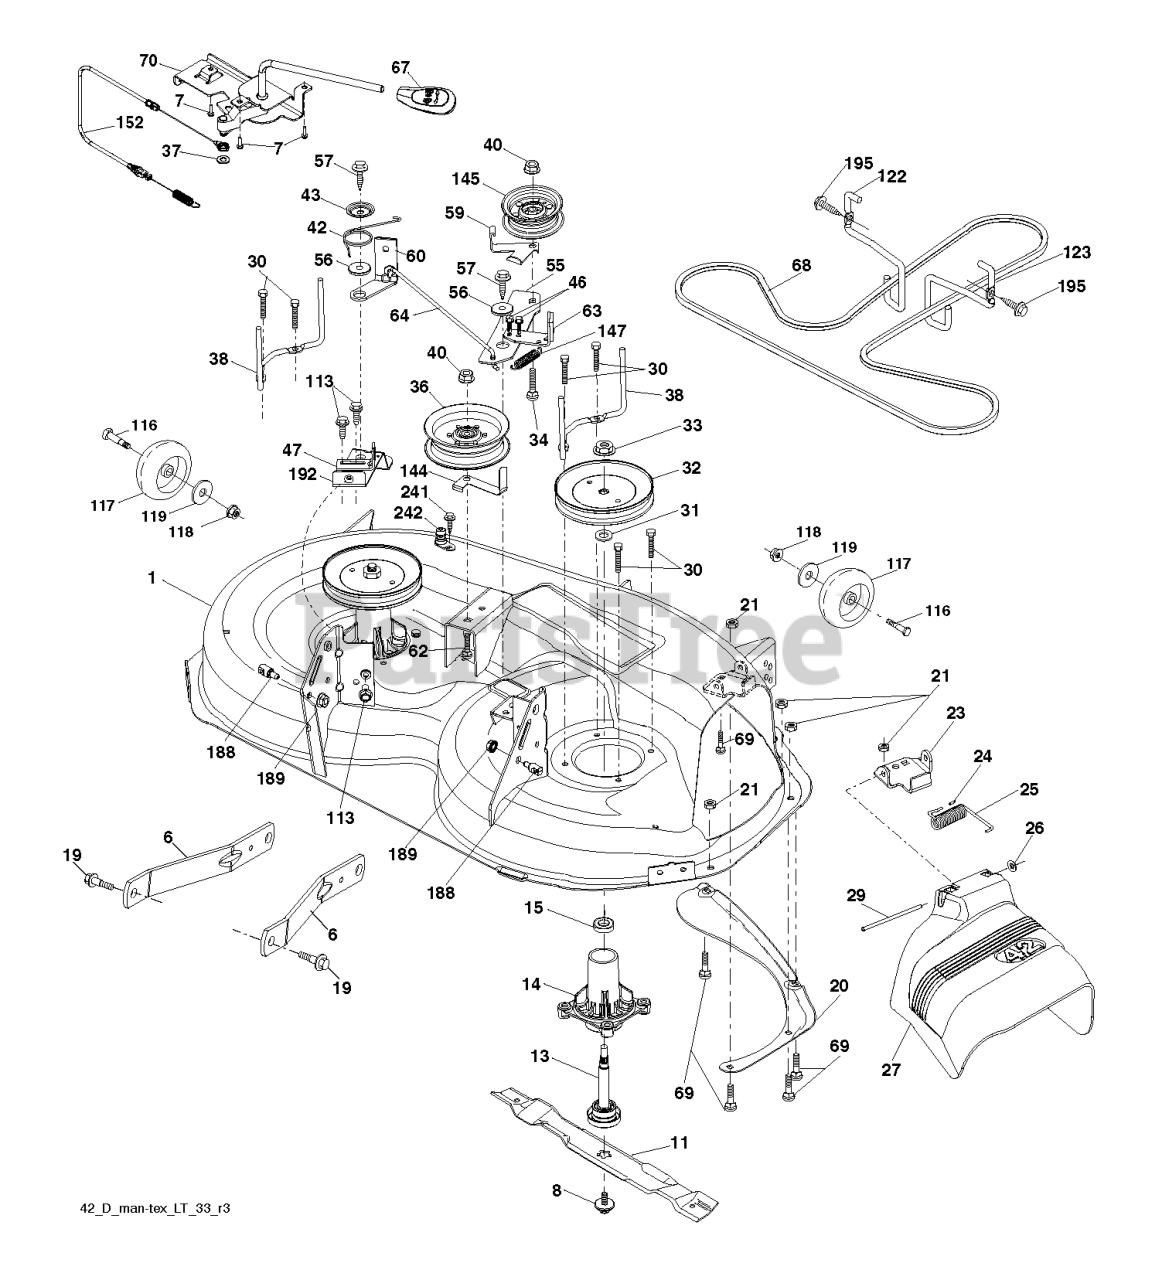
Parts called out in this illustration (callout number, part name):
1	DECK.WELDMNT.42"GREYMS498
6	ARM.SUSPENSION.MOWER.R
7	SCREW.#10 X 0.750.BOS
8	BOLT.WASHER.ASM.7/16-2
11	42" HI-LIFT BLADE
13	SHAFT.ASM.MDRL.N/GREASE.38
14	RP.HOUSING.MANDREL.4PT.
19	BOLT.SHOULDER
20	BAFFLE.VORTEX
21	LOCKNUT
23	BRKT.DEFLECTOR.38"2005+
24	CAP-SLEEVE LT
25	SPRING.TORSION.DEFLECT
26	NUT PUSH M
27	SHIELD.DEFLECTOR.MOWER.42"BLAC
29	ROD.HINGE
30	SCREW, WASHER HEAD
31	WASHER.SPACER.MANDREL
32	PULLEY.MANDREL.5.438.PD
33	NUT.FLANGE.LOCK.TOP
34	BOLT.3/8-16X1.50
36	PULLEY.IDLER.2006
37	WASHER
38	KEEPER.BELT.MANDREL.PULLEY
40	NUT LOCK FLG 3/8-16 UNC
42	SPRING.TORSION.BRAKE
43	SRPING.TORSION.RETAINE
46	SCREW.1/4-20X5/8
47	BRKT.CLUTCH.CABLE
55	IDLER.ARM.42"
56	SPACER.RETAINER
57	SCREW 3/8-16X1
59	GUARD, BELT
60	ARM BRAKE MOWER
63	ARM BRAKE MOWER
64	LINKAGE.BRAKE.ASM.ZINC
67	HANDLE.CLUTCH.CABLE.LT
68	BELT.DECK.DRIVE.42"
69	BOLT
70	CLUTCH.ASM.MANUAL.YT.PREDATORQ
113	BOLT.5/16HEX.WHS.HD
116	BOLT M
117	WHEEL.GAGE.HALF.SPOKED
118	LOCKNUT
119	WASHER.5/16.FLAT.STE.STD.
122	KEEPER BELT ENGINE LH
123	KEEPER BELT RH
144	KEEPER.BELT.MOWER
145	PULLEY.IDLER.48"PRIMARY
147	RETURN SPRING
152	CABLE.CLUTCH.CABLE.W/SPRING
188	STUD.FASTNER.W/ANTI-ROTATE
189	NUT LOCK HEX FLANGE 5/16-18
192	BRKT.BRAKE.STAND.LH.
195	SCREW, 3/8-16X3/4
241	SCREW.TT.#10-32X.5.3/8.FLANGE
242	PORT.WASHOUT
